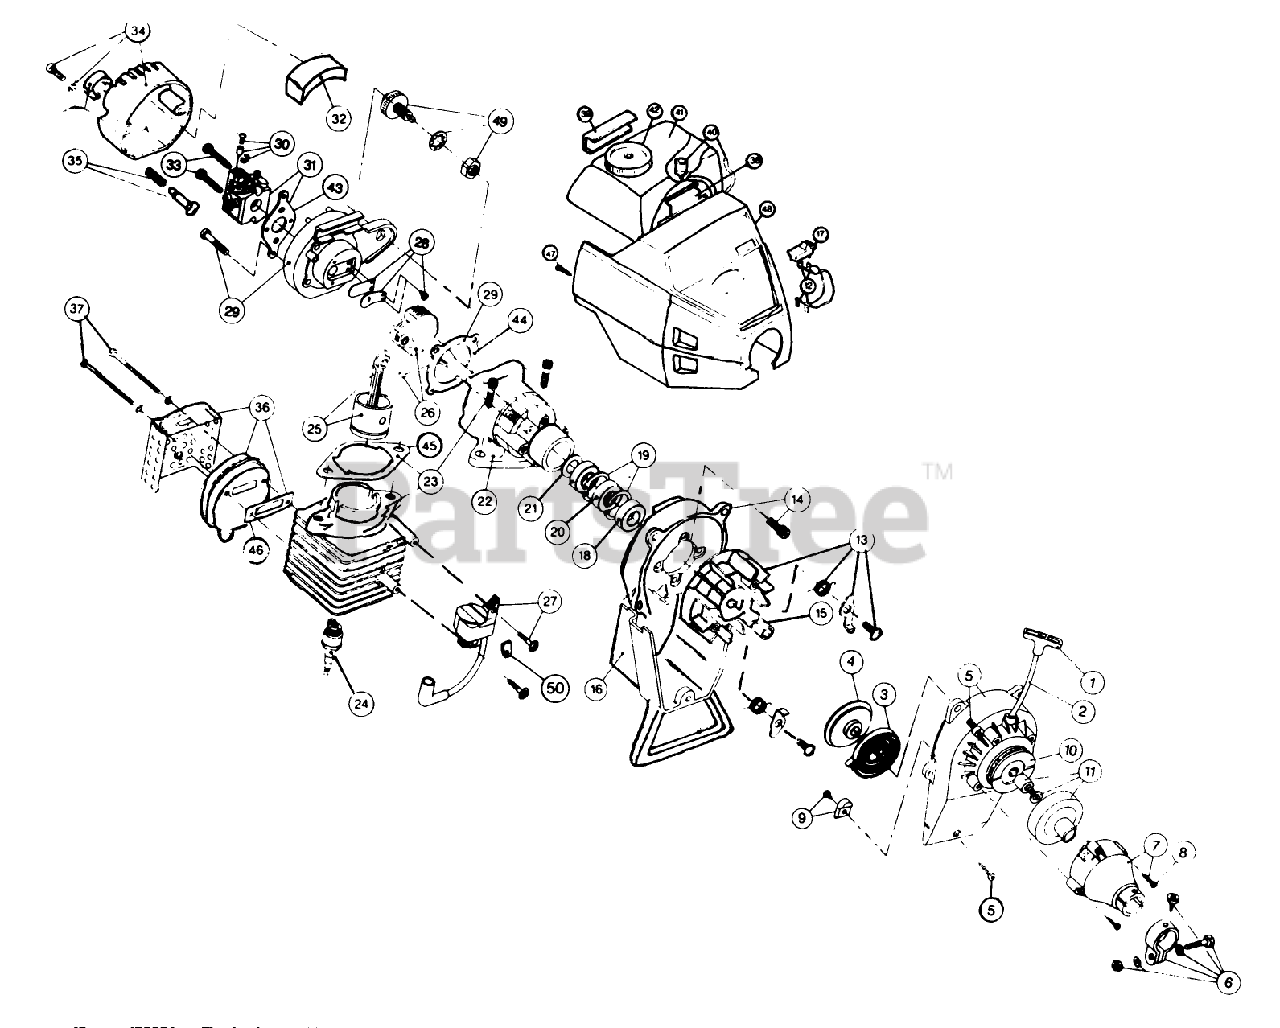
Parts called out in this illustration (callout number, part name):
6	CLAMP ASM - UPPER
14	SHROUD ASM
18	OUTER BEARING
20	SEAL
21	INNER BEARING ASM
24	SPARK PLUG
30	THROTTLE ADJ ASM
37	MUFFLER MOUNTING BOLTS
38	FRONT MOUNTING PAD
39	REAR MOUNTING PAD
40	FUEL LINE ASM
43	CARB.GASKET
49	PRIMER BULB/HOSE ASM
57	FLYWHEEL KEY (10-PK)
